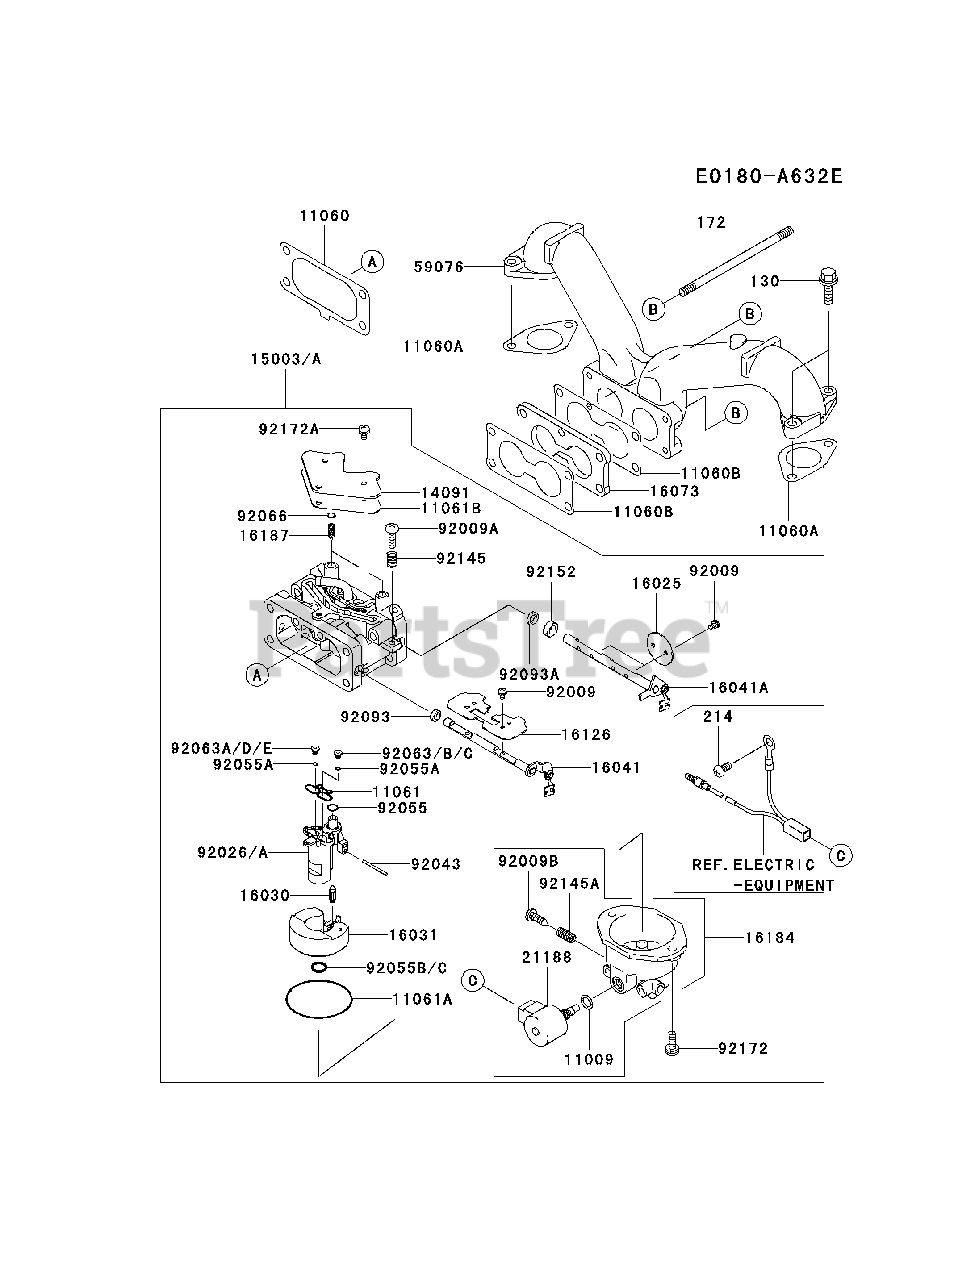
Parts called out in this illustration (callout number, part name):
130	BOLT-FLANGED
172	BOLT-STUD
214	SCREW-PAN+-
